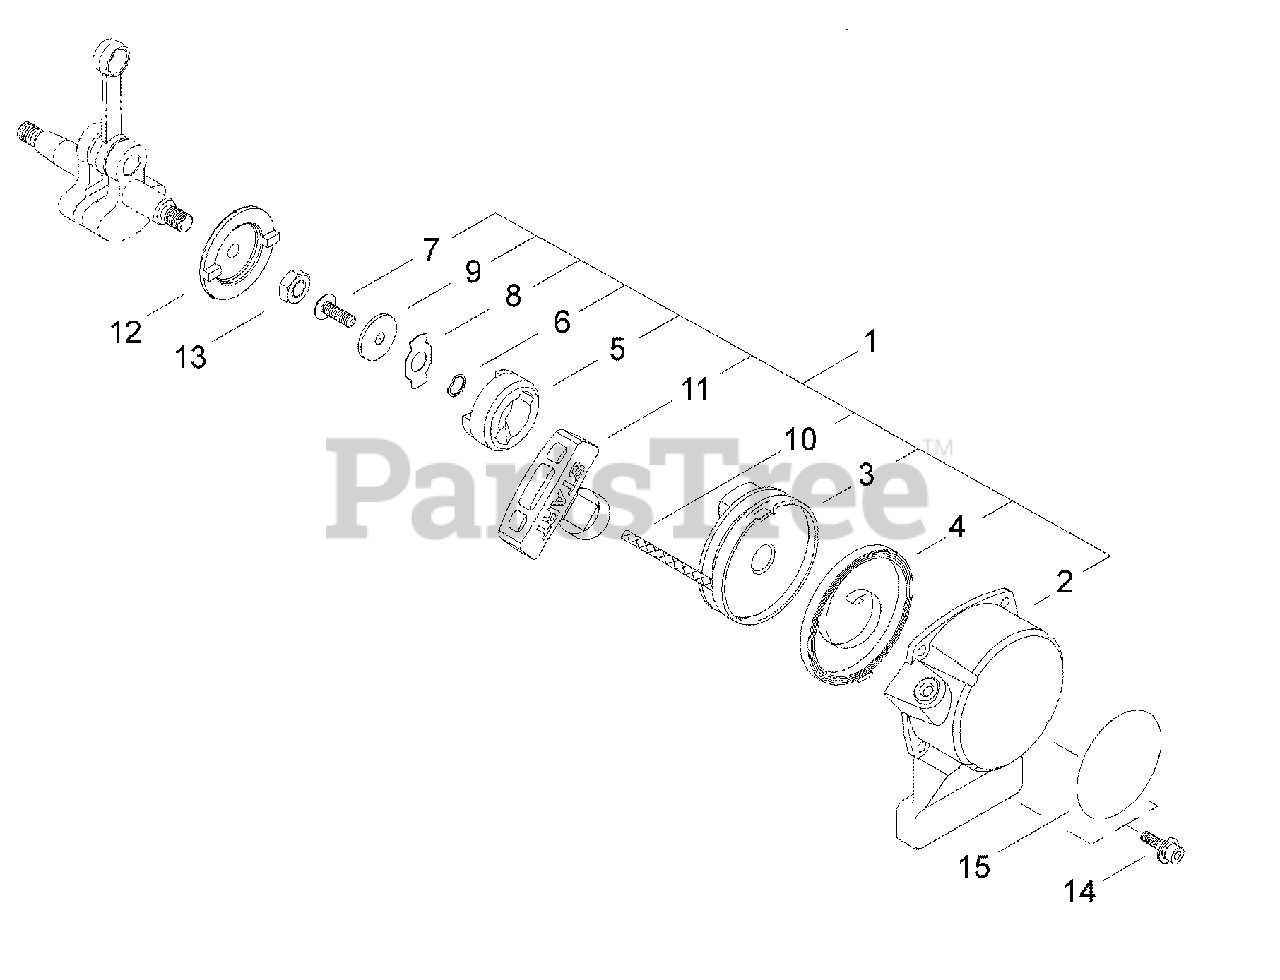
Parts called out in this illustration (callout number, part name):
1	STARTER ASSY
2	CASE, STARTER
3	REEL, ROPE
4	SPRING, REWIND
5	PAWL, STARTER
6	WASHER - SPRING
7	SCREW - 5
8	RETAINER
9	WASHER - 5
10	ROPE, STARTER
11	GRIP, STARTER
12	PAWL
13	NUT - 8
14	SCREW - 4X16
15	LABEL - C4
